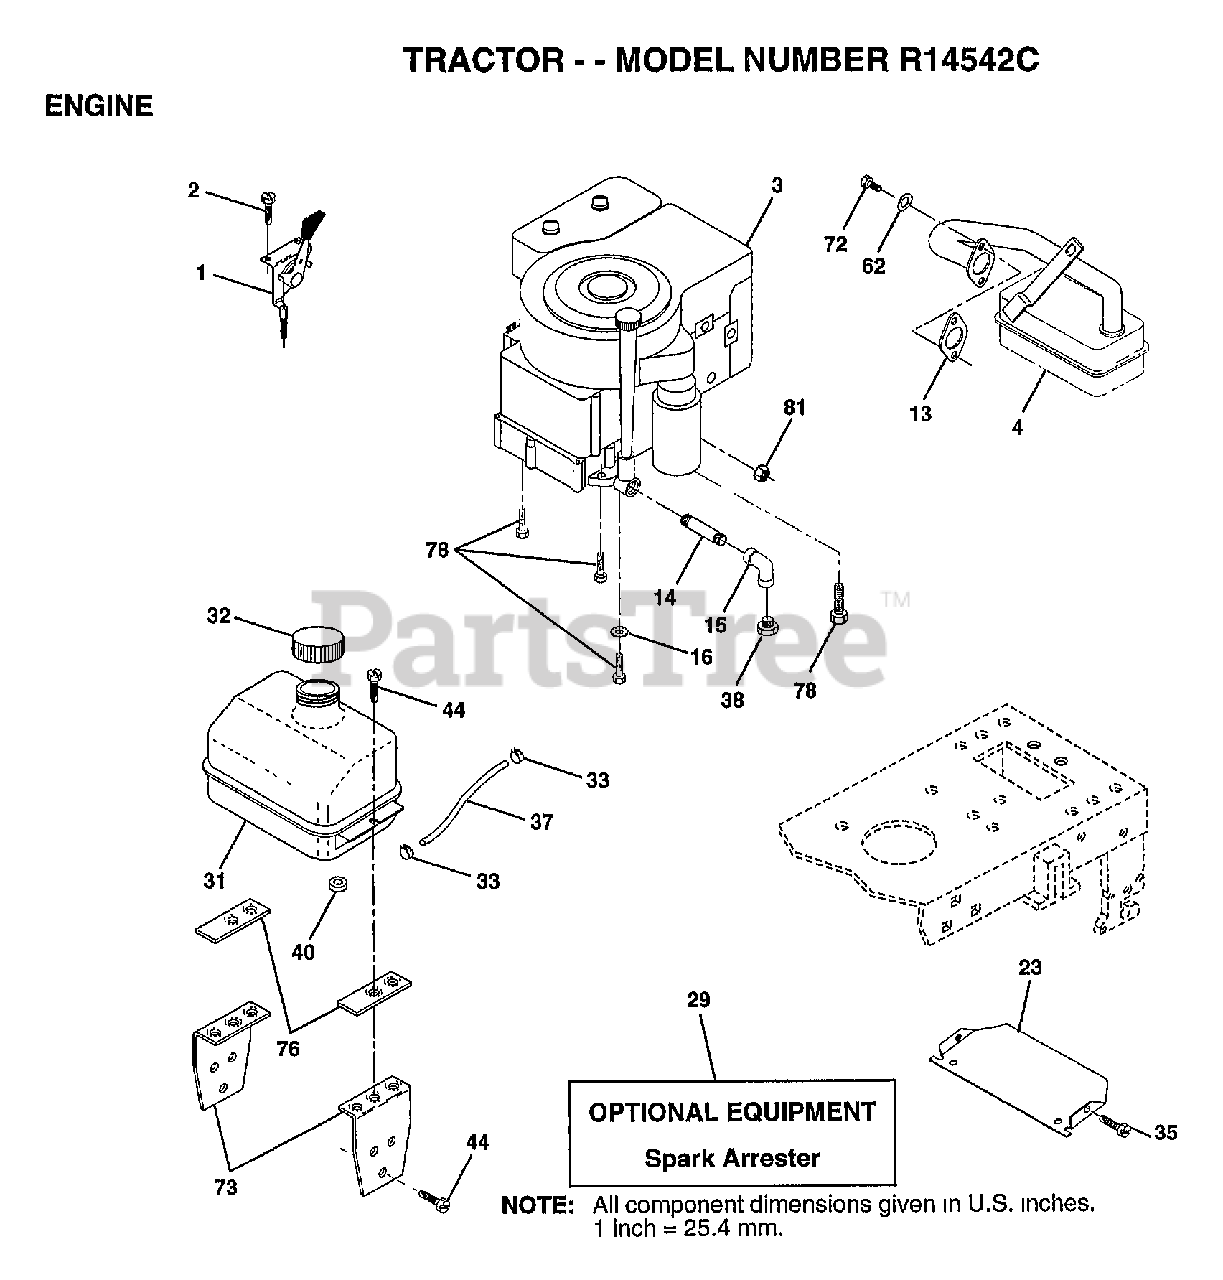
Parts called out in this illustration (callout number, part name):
1	THROTTLE CONTROL
2	SCREW LT
4	MUFFLER
13	GASKET ENG 1 313 LD TIN PLATED
14	PIPE NIPPLE
15	ELBOW
16	LOCKWASHER
23	SHIELD-HEAT
31	TANK.FUEL.LT.
32	CAP ASM FUEL
33	HOSE CLAMP
35	SCREW
37	LINE FUEL
44	SCREW
62	LOCKWASHER
72	SCREW
73	BRKT FUEL TANK T
76	"CLAMP,FUEL TANK T"
78	SCREW
81	NUT
